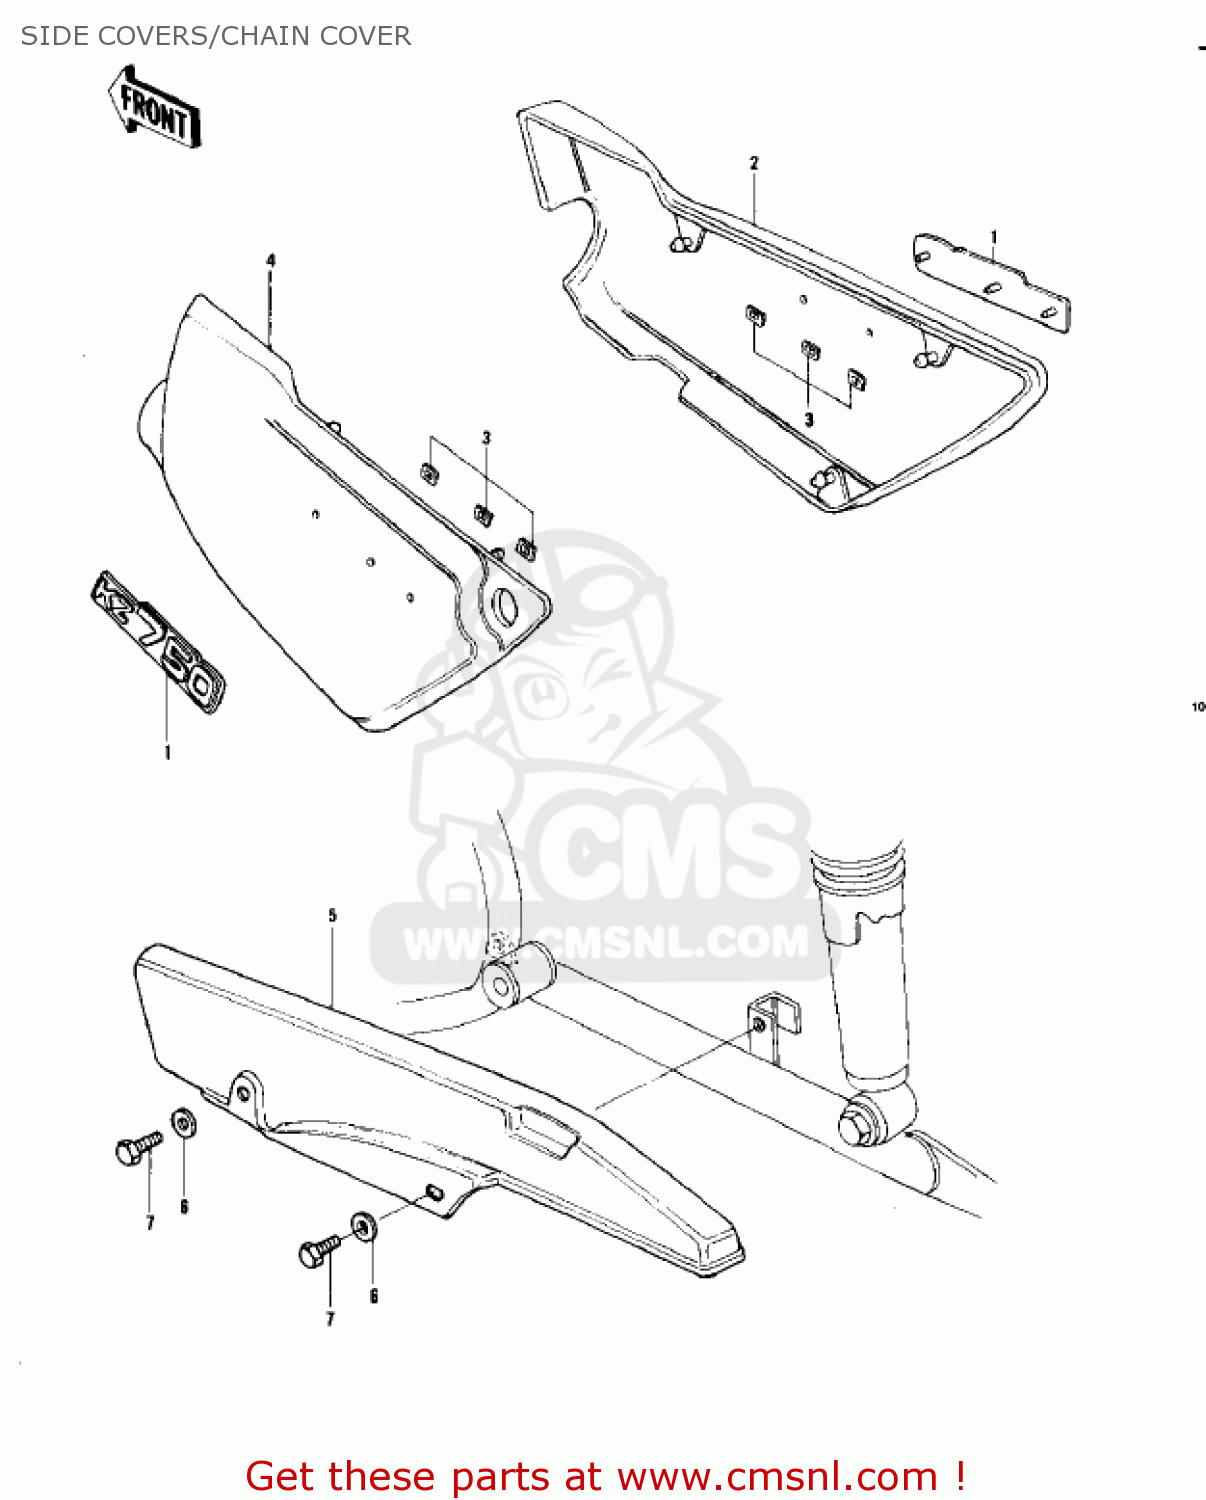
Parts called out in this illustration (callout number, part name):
1	SIDE COVER MARK
2	COVER,R.H SIDE,D.RED
3	NUT,PUSH,3MM
4	COVER,L.H,SIDE,D.RED
5	CHAIN CASE
6	WASHER,8.5X20X1.6
7	BOLT-HEAX HEAD,6X14
